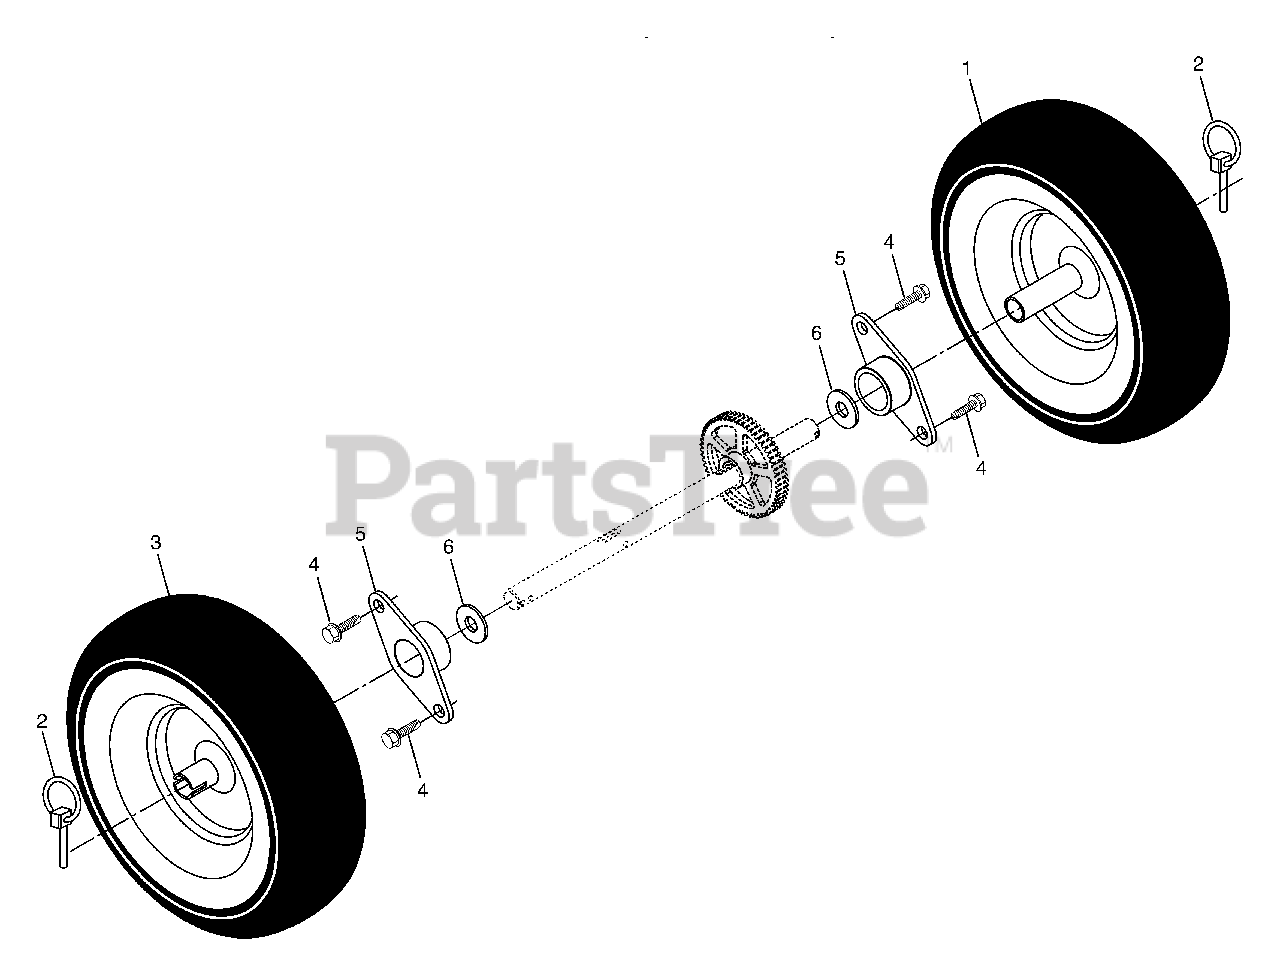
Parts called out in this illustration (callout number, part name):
1	Wheel Assembly, 13", LH
2	Pin, Klik 1/4
3	Wheel Assembly, 13", RH
4	Screw, Hex Head 5/16-18 x 5/8
5	Bearing, Axle
6	Washer, Thrust (1")
